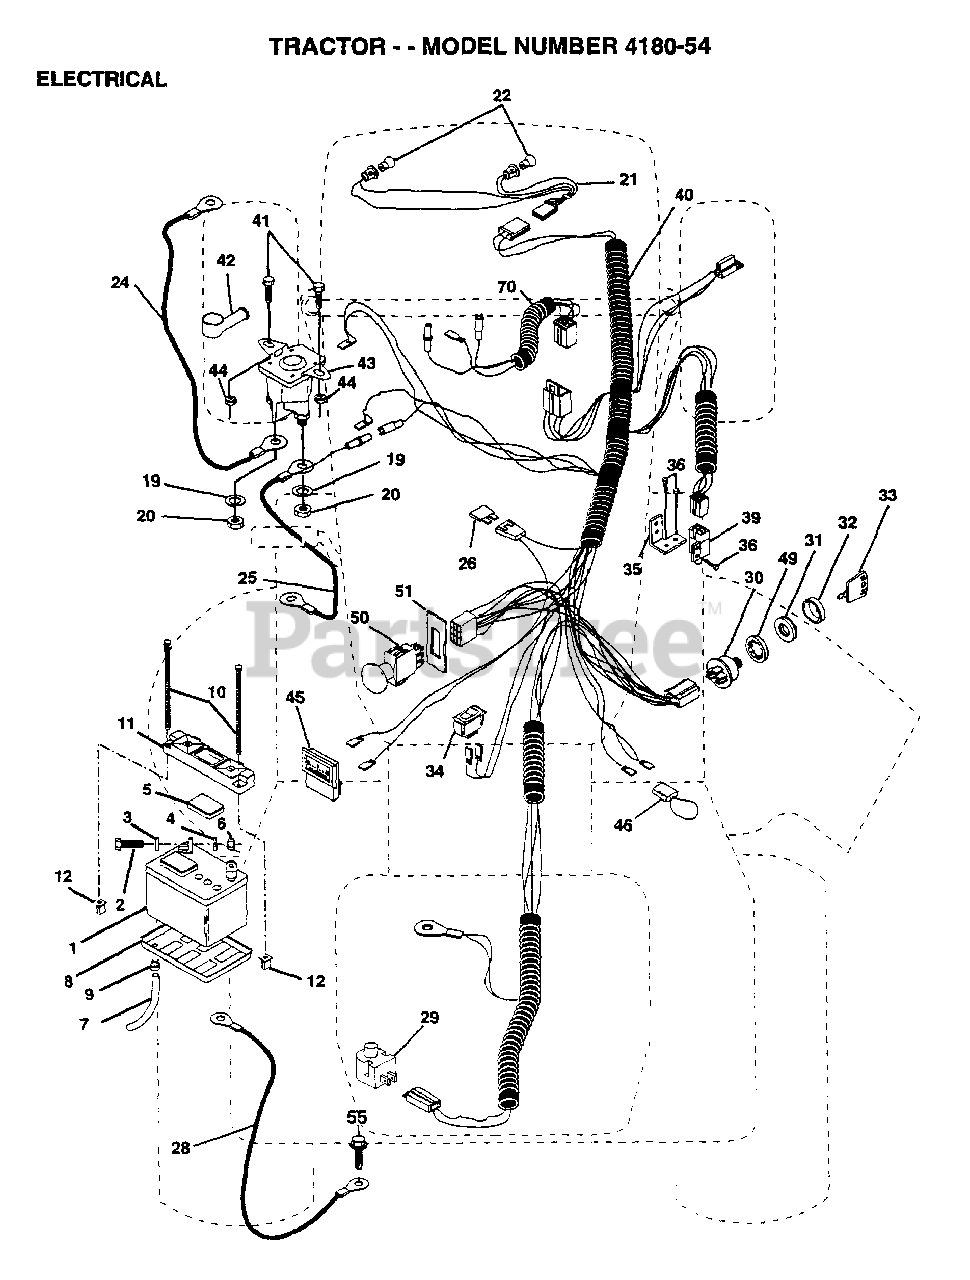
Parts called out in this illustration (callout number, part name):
2	BOLT LT
3	WASHER
4	LOCKWASHER
5	"CAP,BATTERY "
7	"DRAIN TU T, BATT"
8	"TRAY T, BATTERY"
9	HOSE CLAMP T
20	NUT
21	"HARNESS,LIGHT SOC"
22	HEADLAMP BULB
24	"CABLE T, BATTERY"
25	CABLE.6GA.22W/16W
26	FUSE HYT
28	CABLE.GRND.6GA.21
29	SWITCH SEAT
32	COVER KEY SWITCH
33	KEY MLD GEN DELTA
34	SWITCH LT
35	BRACKET LT
36	SCREW
39	SWITCH INTERLOCKT
40	HARNESS.ING.ELEC.
41	BOLT.HX.1/4-20
44	NUT
45	AMMETER
46	PROTECTION LOOP
49	LOCKWASHER
51	RING RETAIN PTO
55	SCREW LT
70	HARNESS ENG B&S
